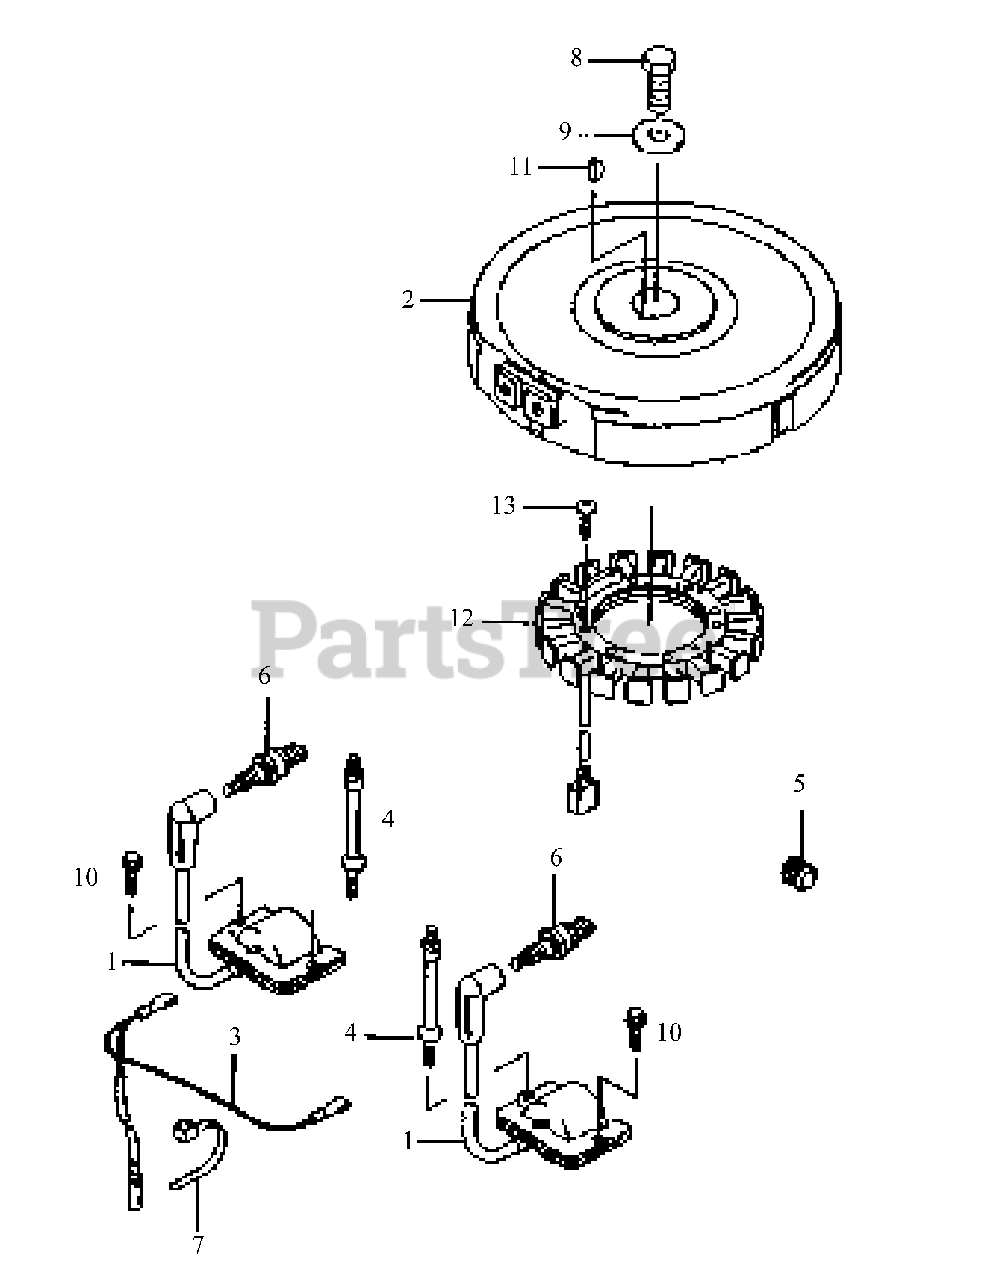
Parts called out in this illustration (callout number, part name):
1	Coil, Ignition
4	Stud
6	Spark Plug
10	Bolt, Flange
11	Key, Woodruff
12	Charging Coil
13	Screw
